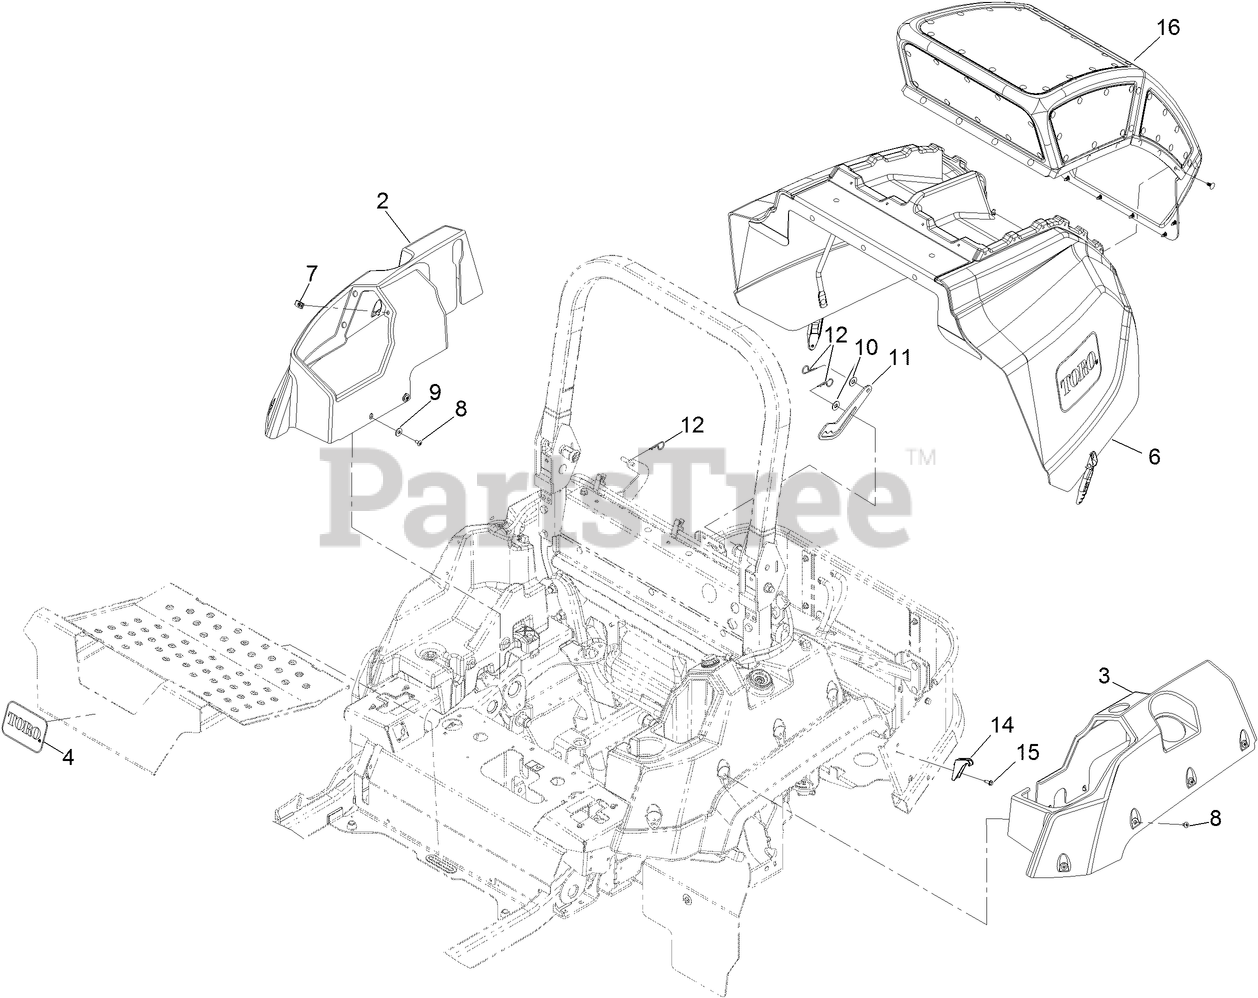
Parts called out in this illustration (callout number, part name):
2	COVER-TANK, RH
3	COVER-TANK, LH
4	DECAL
6	ASM, HOOD LZSD
8	SCREW-TORX
9	WASHER-FLAT
10	WASHER-FLAT
11	PROP-HOOD
12	PIN-COTTER, HAIR
14	LATCH-CATCH
15	SCREW-HWH
16	ASM, HOOD-INTAKE
